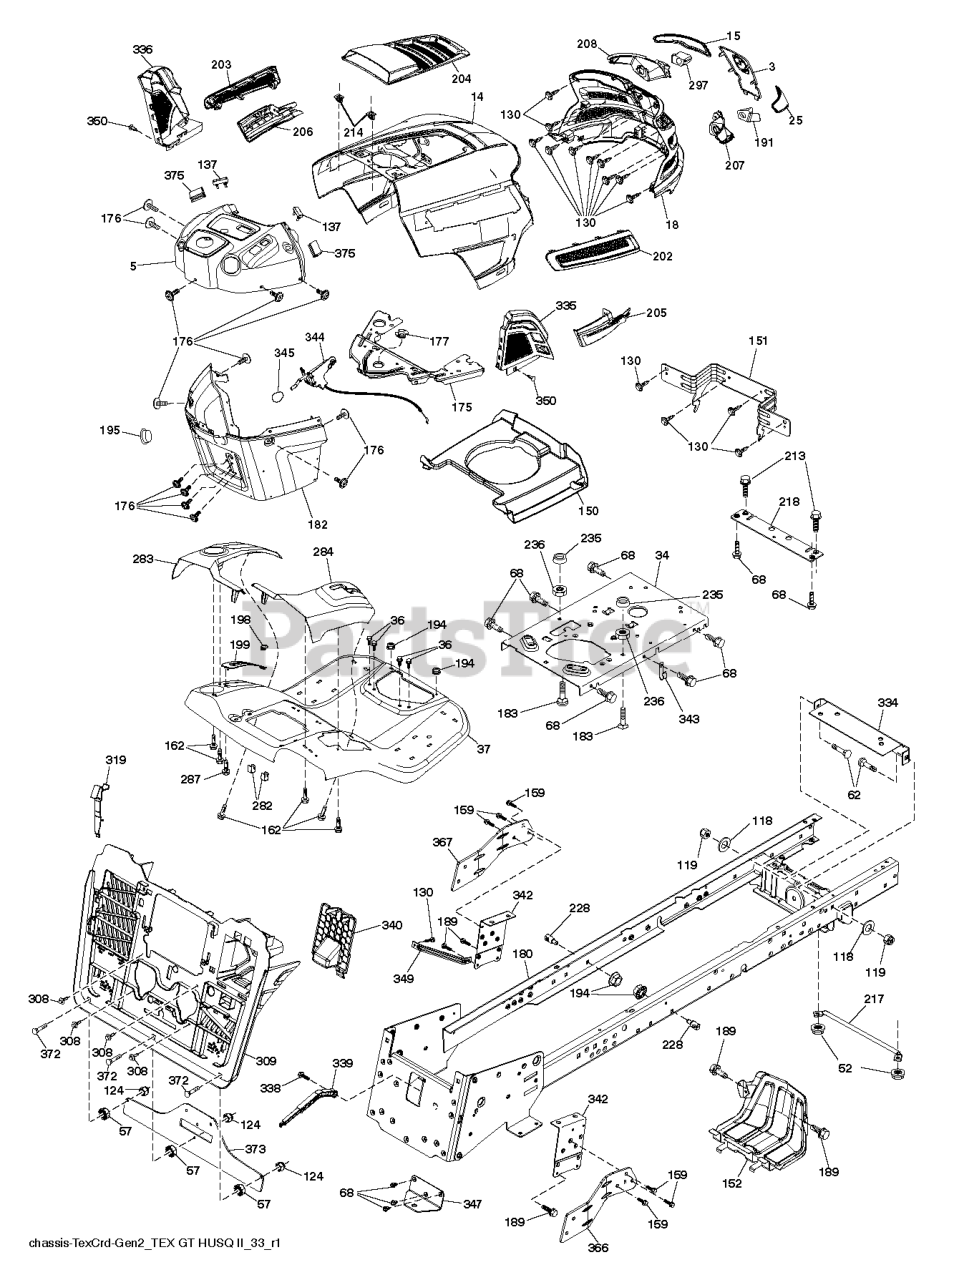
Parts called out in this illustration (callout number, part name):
3	APPLIQUE.SUBASM.GT.HUSQ.II
5	UPPER.GT2.SVC.MINDING.PTO.H.
14	HOOD.ASM.HUSQVARNA.GT.TEX.ORAN
15	LENS.HEADLIGHT.LH.GTII.2011
18	GRILLE.SUBSTRATE.2011.
25	LENS.HEADLIGHT.RH.GTII.2011
34	PLATE.ENGINE.10GA.CRD.GENII
36	SCREW 5/16"
37	FENDER.TEX.SRD.CRD.BASE
52	LOCKNUT
62	BOLT D
68	SCREW LT
118	WASHER
130	SCREW.#10 X 0.750.BOS
137	BUMPER DASH
150	AIR.DUCT.GTV.BLACK
151	BRACKET.PIVOT.HOOD.GT.HUSQ.II
152	SHIELD.BROWNING.PNT.GT.V2
159	SCREW, 3/8-16X3/4
162	SCREW.HI-LO.CONSOLE
175	PLATE.CROSSMEMBER.HUSQ
176	SCREW.#10-24X5/8.RN.QU
177	BUSHING STEERING
180	WELDMENT.CHASSIS.TEX.CRD.GEN.2
182	DASH DASH LOWER
183	BOLT.5/16-18X1-1/4 FULL THD
189	SCREW
191	INSERT.REFLECTIVE.RH.HUSQ.GTII
194	NUT LOCK HEX FLANGE 5/16-18
195	PLUG.HOLE.DASH.LOWER.12V.BLK
198	INDICATOR.DECK.LIFT.RED
199	PLATE DECK LIFT
202	VENT.SIDE.RH.GT.HUSQ.II.
203	VENT.SIDE.LH.GT.HUSQ.II.498
204	VENT.TOP.HUSQ.GT2
205	SIDE.TRIM.RH.GT.HUSQ.II
206	SIDE.TRIM.LH.GT.HUSQ.II.GRAY
207	BEZEL LIGHT.RH.GT.II.MYLAR
208	BEZEL LIGHT.LH.GT.II.MYLAR
213	BOLT
214	CLIP.RETAINER.TINNER.
217	ROD.PIVOT.HOOD
218	X-PIECE.HOOD.STOP.NON/
228	STUD.FASTNER.W/ANTI-ROTATE
234	BUMPER.HOOD.TEX.HUSQVARNA
235	SPACER FENDER
236	NUT.CENTERLOCK.5/16-
282	CLIP.RETAINER.CONSOLE.LT.HUSQ
283	CONSOLE.DECKLIFT.CRDII.498
284	CONSOLE.PEDAL.HYDRO
287	SCREW 1/4X20
297	INSERT.REFLECTIVE.LH.HUSQ.GTII
308	BOLT.5/16-18UNCX3/4 W/SEMS.BLK
309	BACKPLATE.ASM.TEX.CRD.GEN2.1
319	LEVER.BAG.CRDII.ANTIROTATION
334	BRACKET.ENGINE
335	COVER.LOWER.DASH.RH.BLACK
336	COVER-LH.LOWER.DASH.GT2.BLACK
338	BOLT BOLT SHOULDER
339	LEVER LEVER BAGGER
340	BATTERY.DOOR.TEX.CRD.GEN.2,1
342	SUPPORT SUPPORT FENDER
343	CLIP CLIP
344	CONTROL.EZ.MULCH.TEX/CRD
345	RP KNOB.OVAL.TAPERED.3/8-16BLK
347	HITCH HITCH TOW TEX CRD GEN 2
349	BRACKET.SUPPORT.LRVB/CRD
350	CLIP.X-MAS.TREE
366	BRACKET.RH.FRONT.BAGGER.BLACK
367	BRACKET.LH.FRONT.BAGGER.BLACK
368	FULL.LEVER.BAGGER.TEX.CRD
